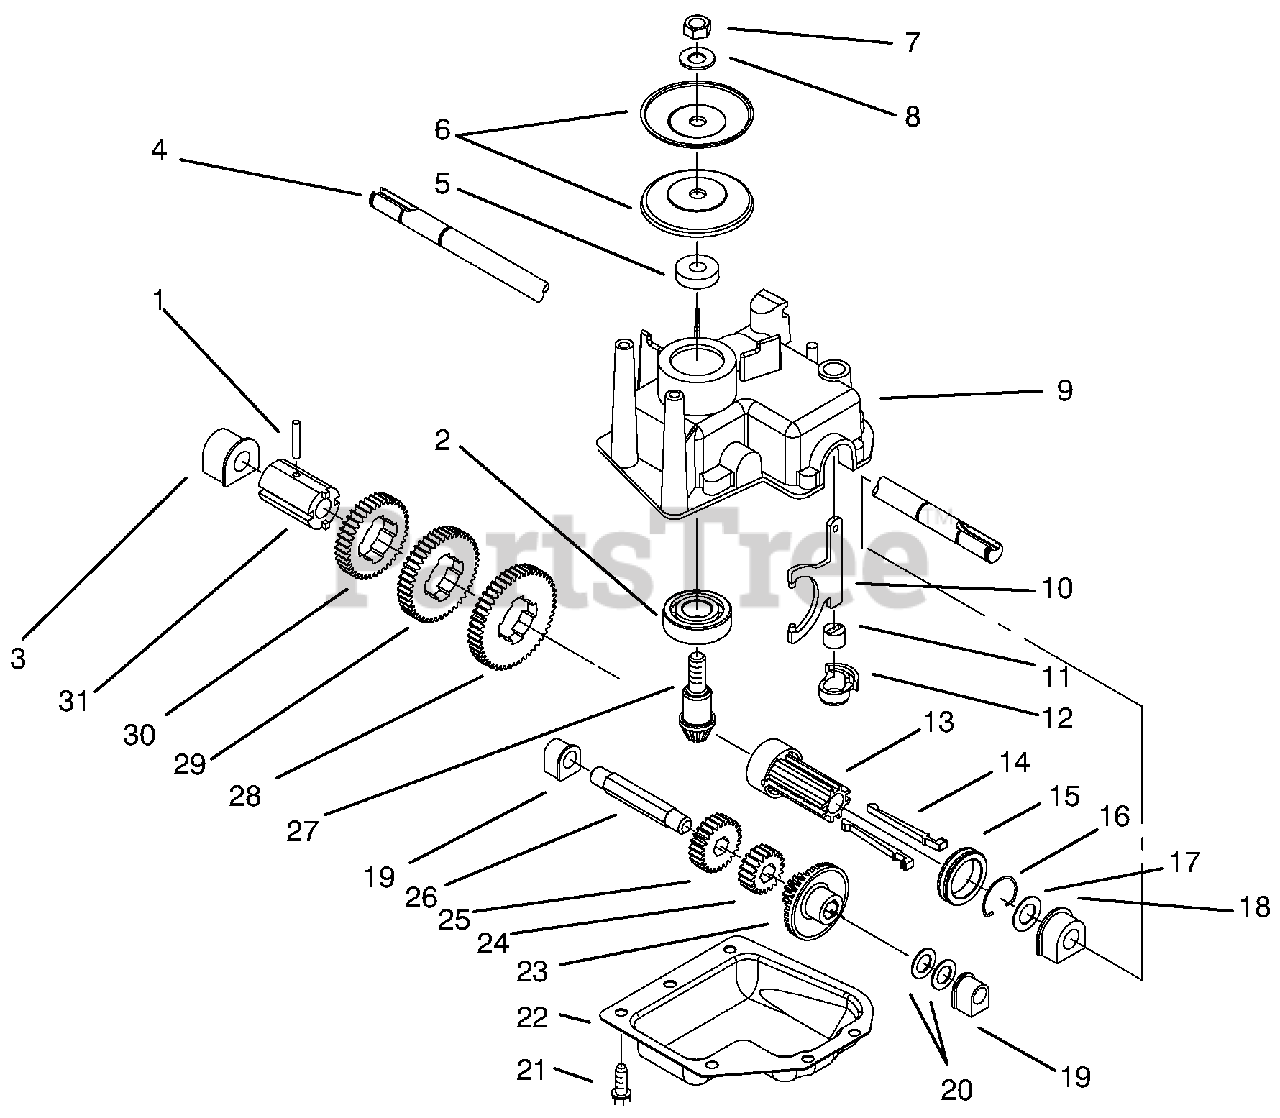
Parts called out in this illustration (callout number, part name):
1	Pin-Groove
2	Bearing-Ball
3	Bushing-Output
4	Shaft-Output
6	Pulley-Half
9	Gearcase-Upper
10	Yoke-Shift
11	Bushing-Yoke
12	Retainer-Shift Fork
13	Sleeve-Shift Key
14	Key-Shift
15	Collar-Shift
16	Clip-Spring
18	Bushing-Output
19	Bushing-Inter. Shaft
20	Washer-Thrust
22	Gear Case Cover
23	Pinion-15 Tooth
24	Pinion-20 Tooth
25	Pinion-25 Tooth
26	Shaft-Intermediate
27	Pinion-Bevel
28	Gear-49Tooth
29	Gear-44Tooth
30	Gear-39 Tooth
31	Sleeve-Gear
